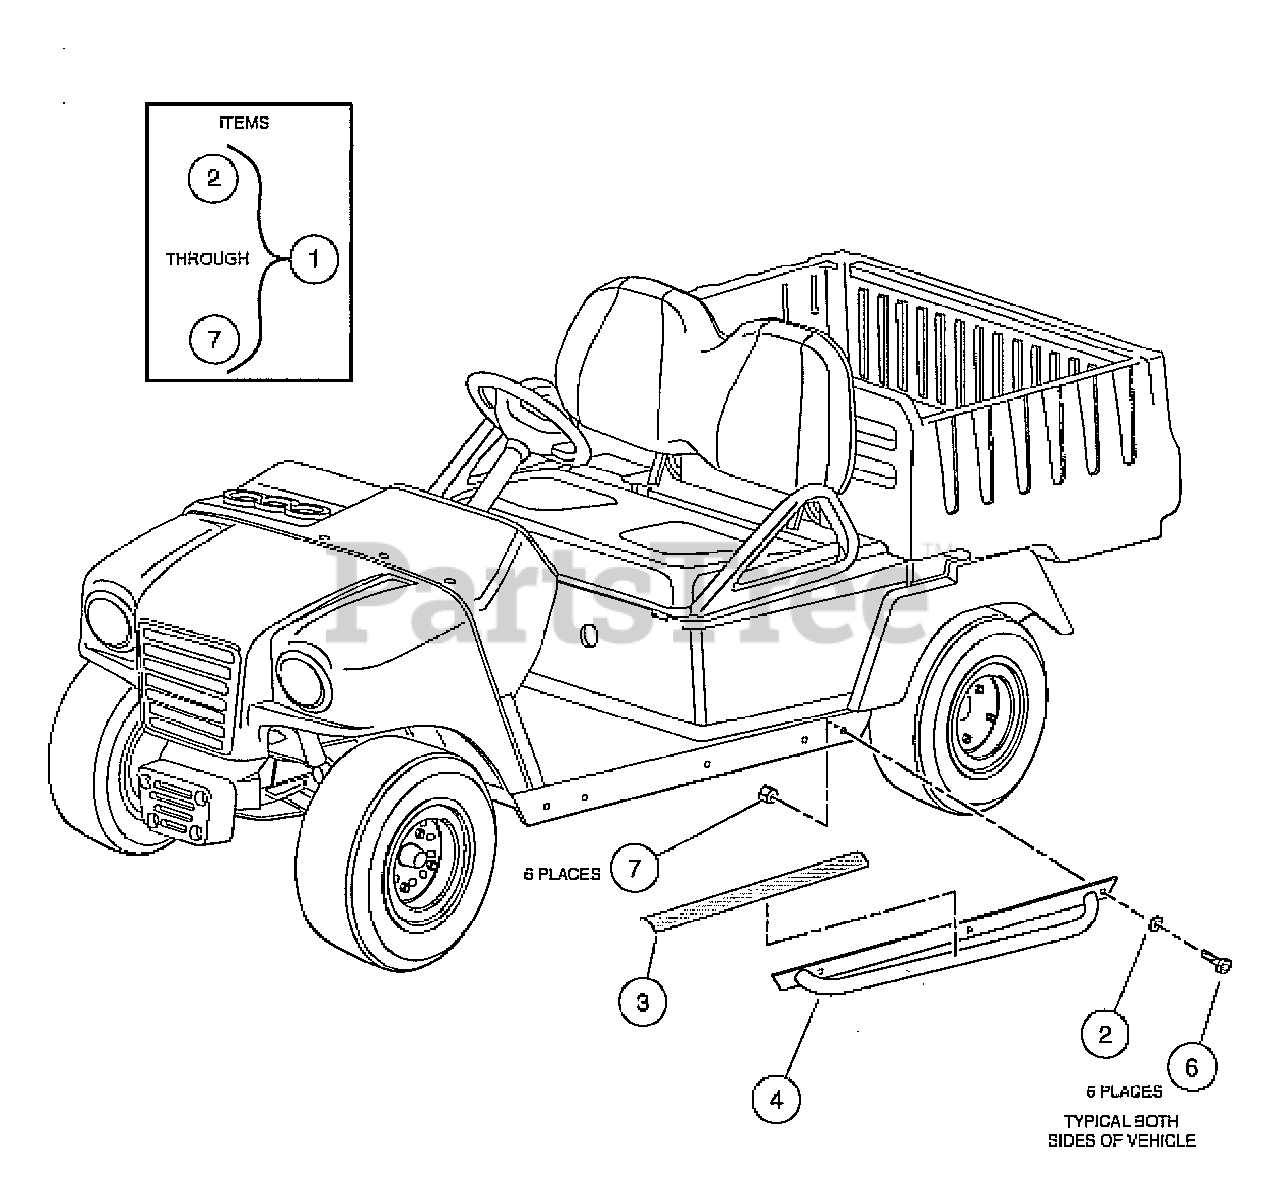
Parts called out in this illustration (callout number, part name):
1	Kit, Neff Bar (Orange)
2	Washer, 3/8 Plat
3	Tape, Non-skid
4	Asm, Neff Bar, Driver (orange)
5	Asm, Neff Bar, Passenger (orange)
6	Screw, 3/8-16 X 1.00 Hx I-Id Cap
7	Locknut, 3/8-16 Hex
